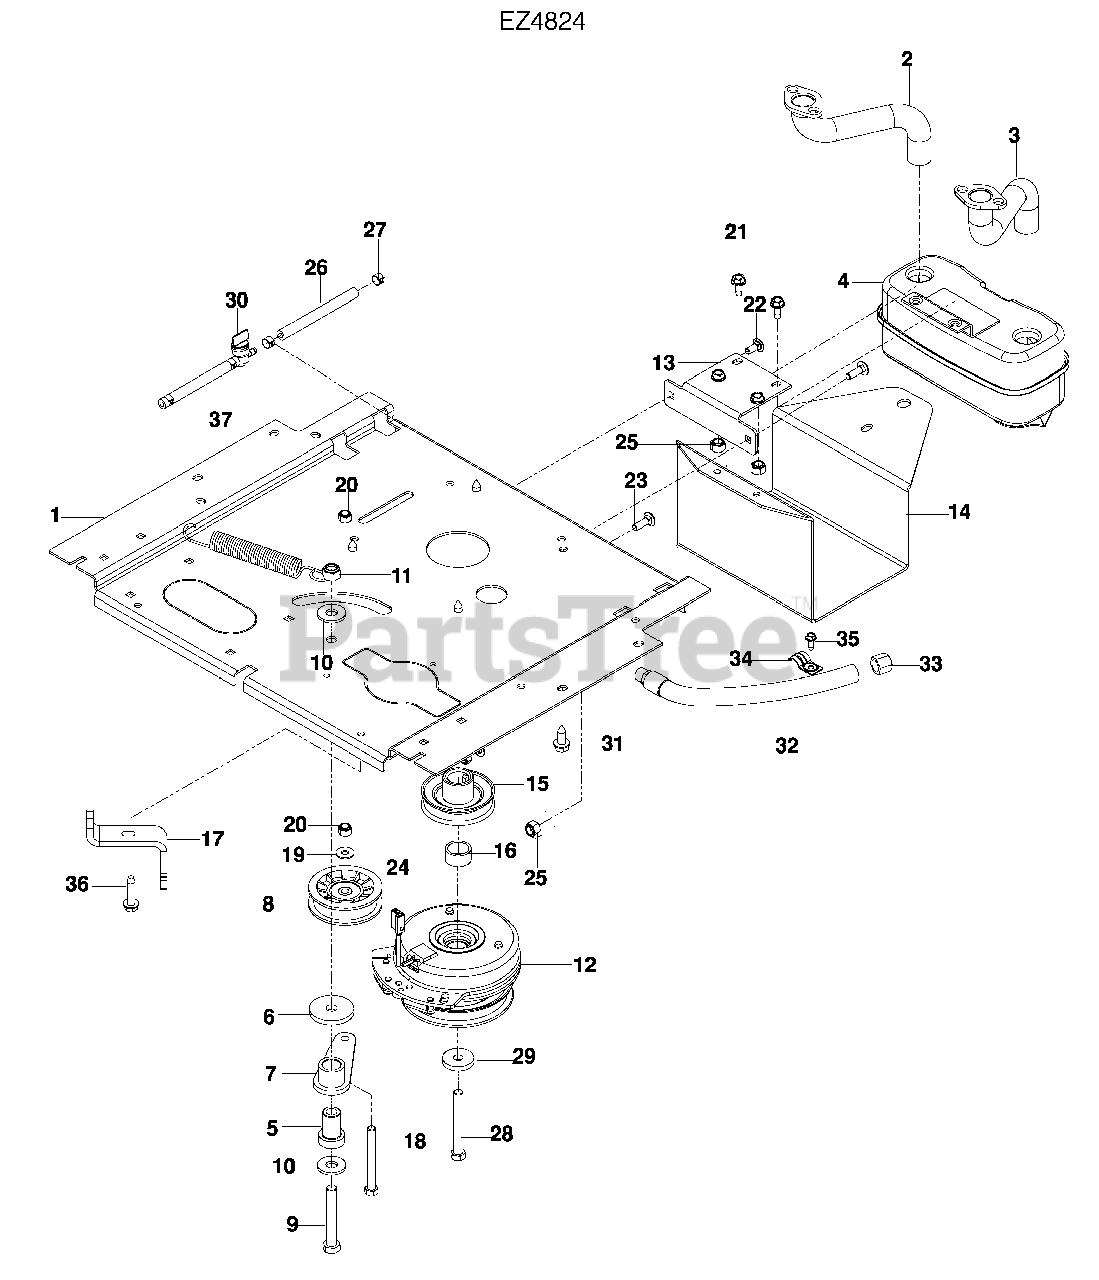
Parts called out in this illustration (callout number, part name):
1	PLATE, ENGINE
2	EXHAUST TUBE, RT
3	EXHAUST TUBE, LT
4	MUFFLER ASM TWIN
5	SPINDLE, IDLER
6	WASHER, HEAVY
7	ARM, IDLER
8	PULLEY, IDLER
9	HCS ½-13 x 3¼
10	WASHER ½ FLAT
11	NUT ½ HEX NYLOC
12	CLUTCH, 105 FT/LBS
13	BRACKET, MUFFLER
14	GUARD, MUFFLER
15	PULLEY, ENGINE
17	STOP, CLUTCH
18	HCS 3/8-16 x 3½ TPBLT
19	WASHER 5/16 STD FLAT
20	NUT 3/8-16 HEX NYLOC
21	BOLT 5/16-18 x ¾ THD FRM
22	RHSNB 5/16-18 x ¾
23	RHSNB 5/16-18 x 1
24	HARNESS, CLUTCH
25	NUT 5/16-18 FLANGE NYLOC
26	FUEL LINE 5"
27	CLAMP, HOSE
28	HCS 7/16-20 x 3½
29	WASHER, CLUTCH
30	VALVE, FUEL
31	HHFS 3/8-16 x 1 THD FRM
32	HOSE, DRAIN
35	SCREW ¼-20 x 5/8 SLF TAP
36	BOLT 3/8-16 x 1½ THD FRM
37	SPRING, DECK DRIVE
